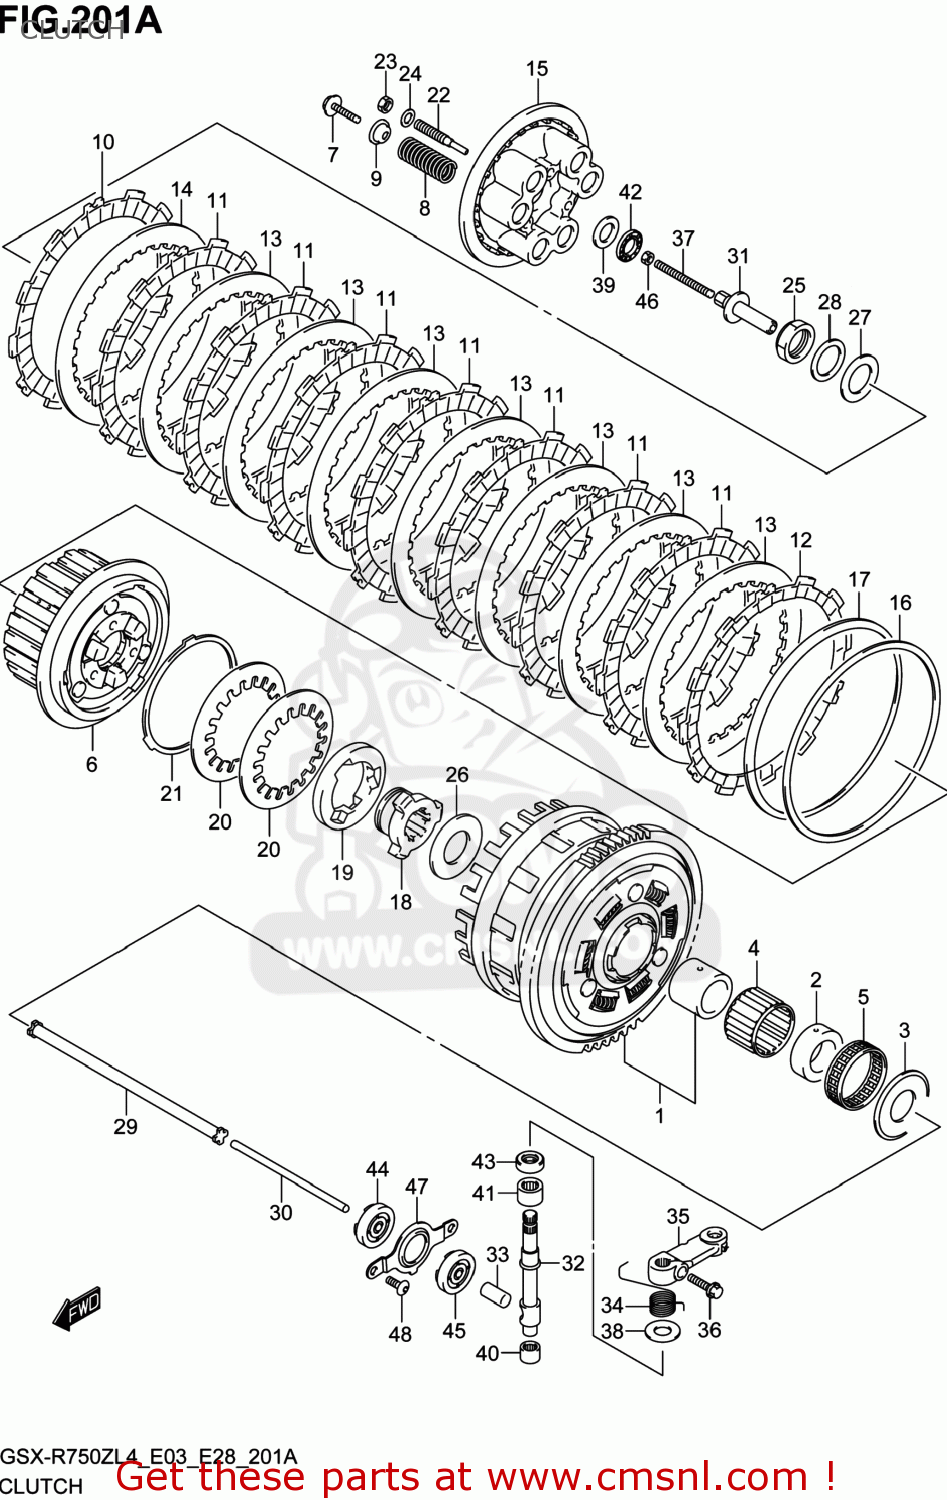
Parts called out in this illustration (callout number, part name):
1	GEAR ASSY,PRI DRIVEN
2	SPACER,OIL PUMP DRIVE SPROCKET
3	WASHER(25X54X2.4)
4	BEARING(35X40X26.8)
5	BEARING(35X40X12)
6	HUB,CLUTCH SLEEVE
7	BOLT,CLUTCH SPRING
8	SPRING,CLUTCH
9	WASHER
10	PLATE,CLUTCH DRIVE (NAS)
11	PLATE,CLUTCH DRIVE NO.1 (NAS)
12	PLATE,CLUTCH DRIVE NO.3 (NAS)
13	PLATE,CLUTCH DRIVEN (NAS)
14	PLATE,CLUTCH DRIVEN (NAS)
15	DISC,CLUTCH PRESSURE
16	SEAT,WAVE WASHER
17	WASHER,CLUTCH PLATE WAVE
18	CAM,CLUTCH DRIVE
19	CAM,CLUTCH DRIVEN
20	WASHER,CAM REACTION WAVE
21	WASHER,CAM REACTION SEAT
22	LIFTER,CLUTCH PRESSURE DISC
23	NUT,CL PRESS DISC LIFTER LOCK
24	SHIM(8.8X14X1)
25	NUT
26	WASHER(25X50X2.5)
27	WASHER
28	WASHER(25X41X2.5)
29	ROD,CLUTCH PUSH,R
30	ROD,CLUTCH PUSH,L
31	PIECE,CLUTCH PUSH
32	CAMSHAFT,CLUTCH RELEASE
33	CAP,CLUTCH PUSH ROD
34	SPRING,CLUTCH RELEASE RETURN
35	ARM,CLUTCH RELEASE
36	BOLT(6X20)
37	SCREW(6X73)
38	WASHER(10.5X24X1)
39	WASHER(15.5X28X1)
40	BEARING(10X14X10)
41	BEARING(12X18X12)
42	BEARING(15X28X2)
43	SEAL,OIL(10X20X6)
44	SEAL,OIL(6X34X10.5)
45	SEAL,OIL(10X17X5)
46	NUT
47	RETAINER,CL PUSH ROD OIL SEAL
48	SCREW(6X13)
